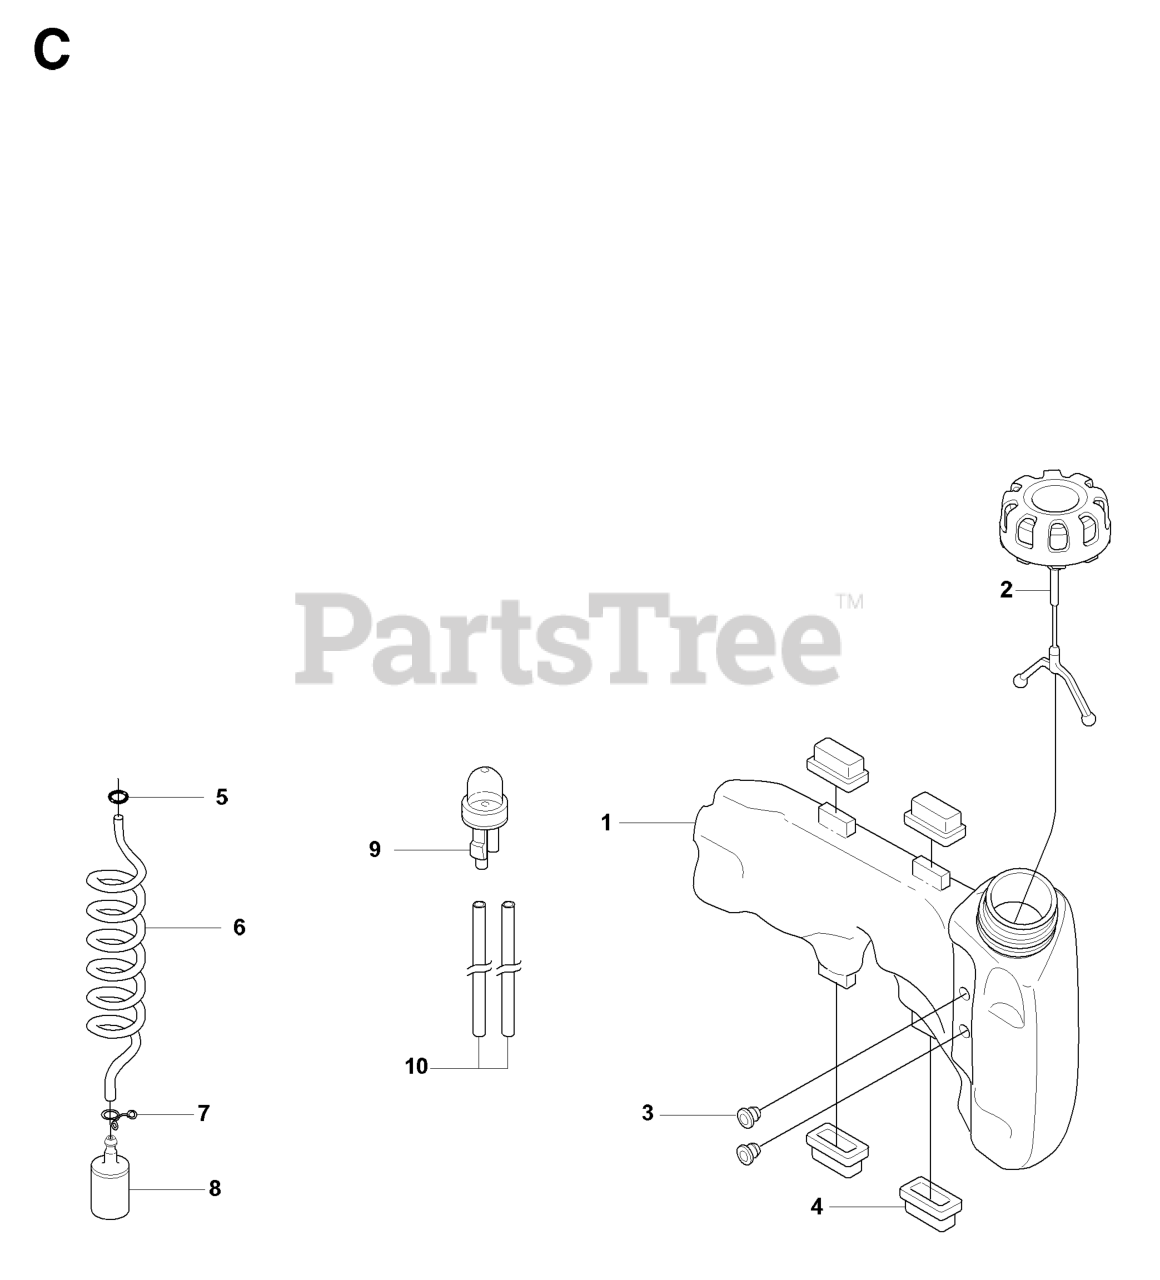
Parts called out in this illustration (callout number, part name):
2	TANK CAP
3	FUEL TANK BUSHING
6	FUEL HOSE
7	HOSE CLAMP
8	RP FUEL FILTER
9	AIR PURGE BUBBLE
10	HOSE
